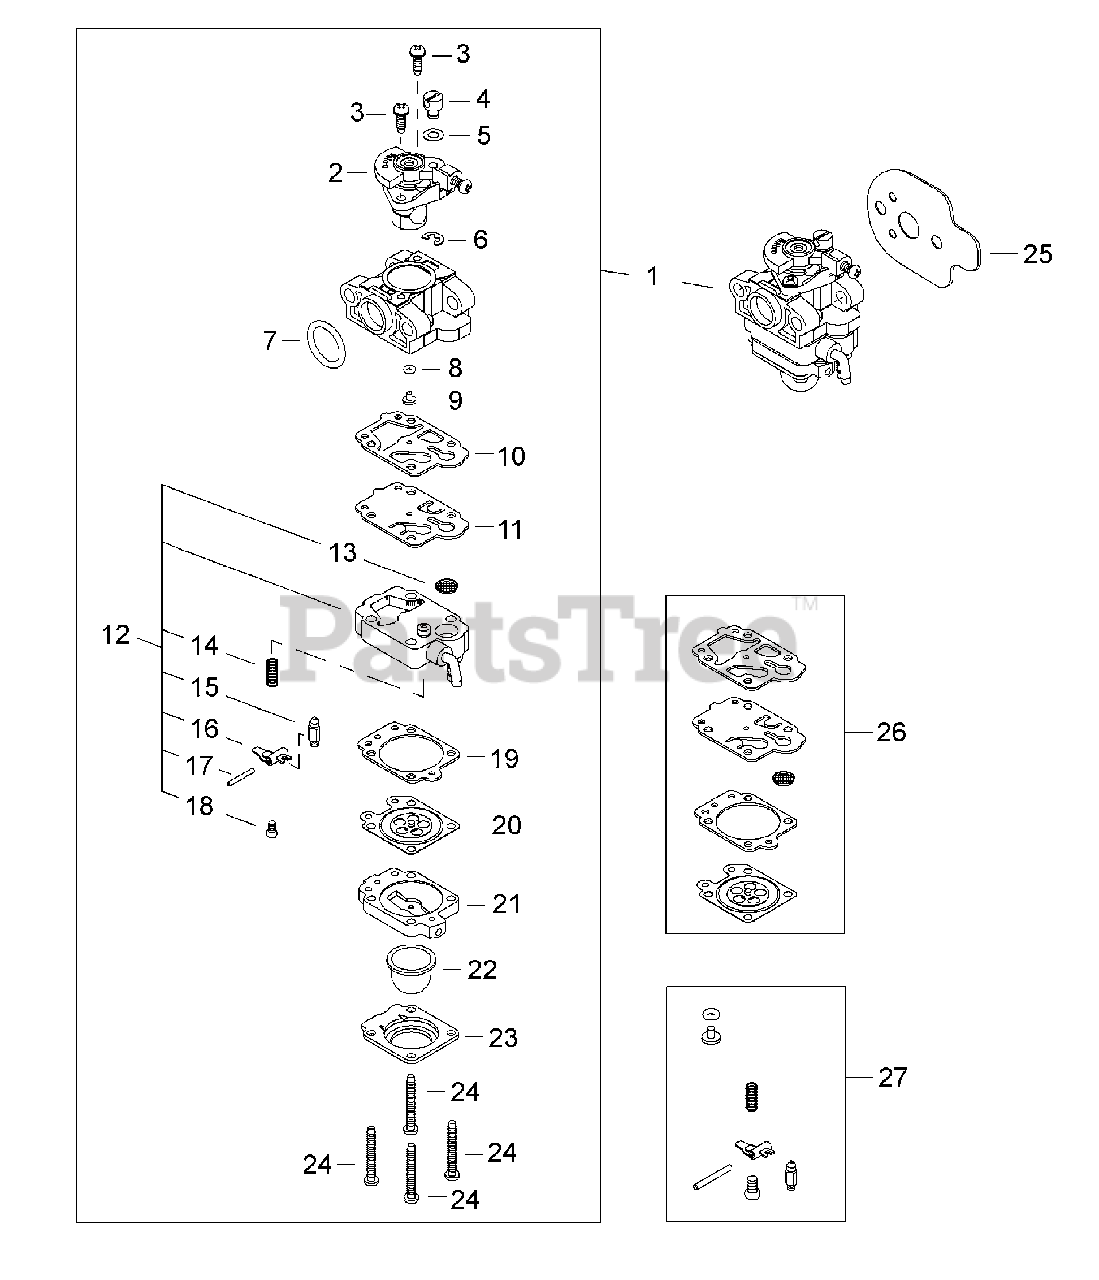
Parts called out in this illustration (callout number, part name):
1	CARBURETOR
2	VALVE ASSY, THROTTLE
3	SCREW, THROTTLE COLLAR
4	SWIVEL
5	WASHER
6	E-RING
7	O-RING 15
8	O-RING
9	JET, MAIN
10	GASKET, PUMP
11	DIAPHRAGM, PUMP
12	BODY ASSY, PUMP
13	SCREEN, FUEL INLET
14	SPRING, METERING LEVER
15	VALVE, INLET NEEDLE
16	LEVER, METERING
17	PIN, METERING LEVER
18	SCREW
19	GASKET, METERING DIAPHRAGM
20	DIAPHRAGM, METERING
21	BODY ASSY, PURGE
22	BULB, PURGE
23	RETAINER, PURGE BULB
24	SCREW
25	GASKET, INTAKE
26	GASKET / DIAPHRAGM KIT
27	VALVE KIT, INLET NEEDLE
